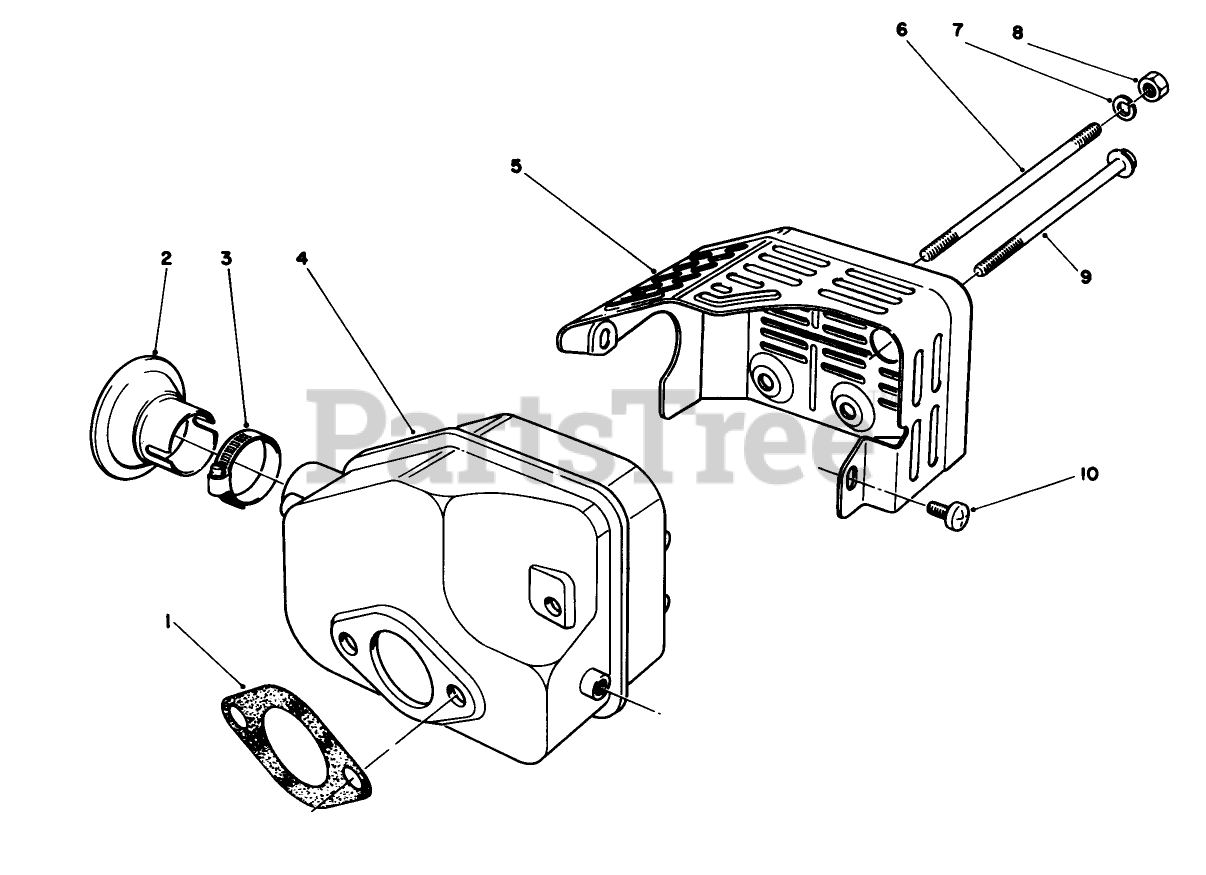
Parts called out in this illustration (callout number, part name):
1	GASKET
3	Clamp
4	MUFFLER
5	COVER-MUFFLER
7	WASHER-LOCK
10	SCREW
